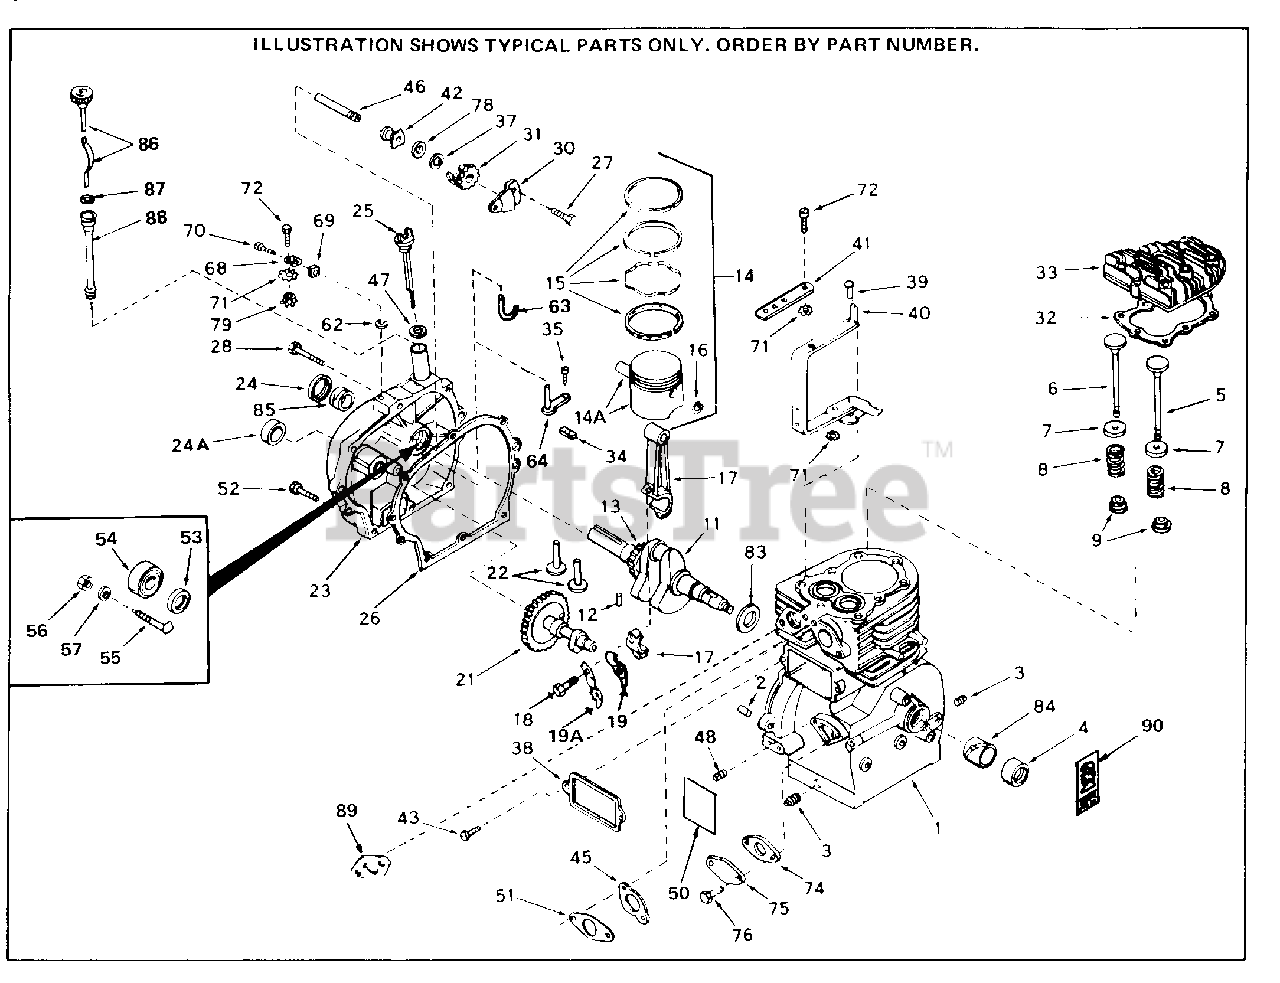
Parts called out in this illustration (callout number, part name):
1	"Cylinder (Incl. 2, 3, 4 & 48) 2-3/4" Bore
2	Dowel Pin
3	Oil Drain Plug (Sq. hd., 1/4-18)
4	Seal, Oil
5	Intake Valve (Std.) (Incl. 9)
5	Intake Valve (1/32" OS) (Incl. 9)
6	Exhaust Valve (Std.)(Incl. 151)
6	Exhaust Valve (1/32" OS) (Incl. 151)
7	Valve Spring Cap
8	Valve Spring
9	Cap, Lower valve spring
11	Crankshaft
12	Pin, Crankshaft gear Only)
13	Crankshaft Gear Early Production Onl y
14	Piston, Pin & Ring Set (Std.) 2-3/4" Bore
14	Piston, Pin & Ring Set (.010" OS)
14	Piston, Pin & Ring Set (.020" OS)
14A	Piston & Pin Ass'y. (Std.) (Incl. 16) 2-3/4"
14A	Piston & Pin Ass'y. (.010" OS) Incl. 16
14A	Piston & Pin Ass'y. (.020" OS) Incl. 16
15	Ring Set (Std.) (2-3/4" Bore)
15	Ring Set (.010" OS)
15	Ring Set (.020" OS)
16	Piston Pin Retaining Ring
17	Rod Assy., Connecting (Incl. 18 & 19)
18	Bolt, Connecting rod (Incl. 2 pcs.)
19	Dipper, Oil
19A	Plate, Lock & Oil dipper This plate m ay be replaced by No. 34242 oil dippe r but No. 650662B screw must be used
21	Camshaft (MCR)
22	Lifter, Valve
23	Cover, Cylinder Incl. 24, 46, 55, 56 & 57
24	Oil Seal quired)
24	Oil Seal equired)
25	Dipstick (Incl. 47)
26	Gasket, Cylinder cover
27	Screw, 10-24 x 1/2"
28	Screw, 1/4-20 x 1-3/4"
30	Bracket, Governor gear
31	Gear Assy., Governor (Incl. 78)
32	Gasket, Head
33	Cylinder Head Not incl. with short b lock
34	Yoke, Governor
35	Screw, 6-40 x 5/16"
37	Retaining Ring
38	Valve Cover Gasket
39	Rivet, Split (Early production only)
40	Lever, Governor New lever does not ne ed oneof Ref. No. 39, 68, 71, 72 & 79
41	Bracket, Governor Adjusting
42	Spool, Governor
43	Screw, 10-24 x 1/2" (Use as required)
45	Intake Pipe Gasket
46	Shaft, Mechanical governor
47	Oil Fill Plug Gasket
48	Plug, Pipe
50	Decal, Instruction
51	Gasket, Carburetor
52	Screw, 1/4-20 x 1-1/4"
53	Washer, Thrust
54	Bearing, Ball
55	Retainer, Bearing
56	Nut, Lock, 10-24
62	Retaining Ring
63	Rod Assy., Governor This one piece go v. rod is no longer used. It is repla ced by 30699C assy., Ref. 64
64	Rod Assy., Governor (Incl. 34 & 35)
68	Governor Lever Clamp y)
69	Lock Nut, 10-32
70	Screw, 10-32 x 3/4"
71	Lock Washer #8
72	Screw, 8-32 x 5/16" (Use as required)
74	Gasket, Fuel pump (Use as required)
75	Cover, Fuel pump pad Use as required
76	Screw, T-30, 1/4-20 x 1/2"
78	WASHER
79	Lock Nut, 8-32
84	Bushing, Crankshaft (Use as required)
85	Bushing, Crankshaft (Use as required)
89	Gasket, Muffler (Use as required)
90	Decal, Name
